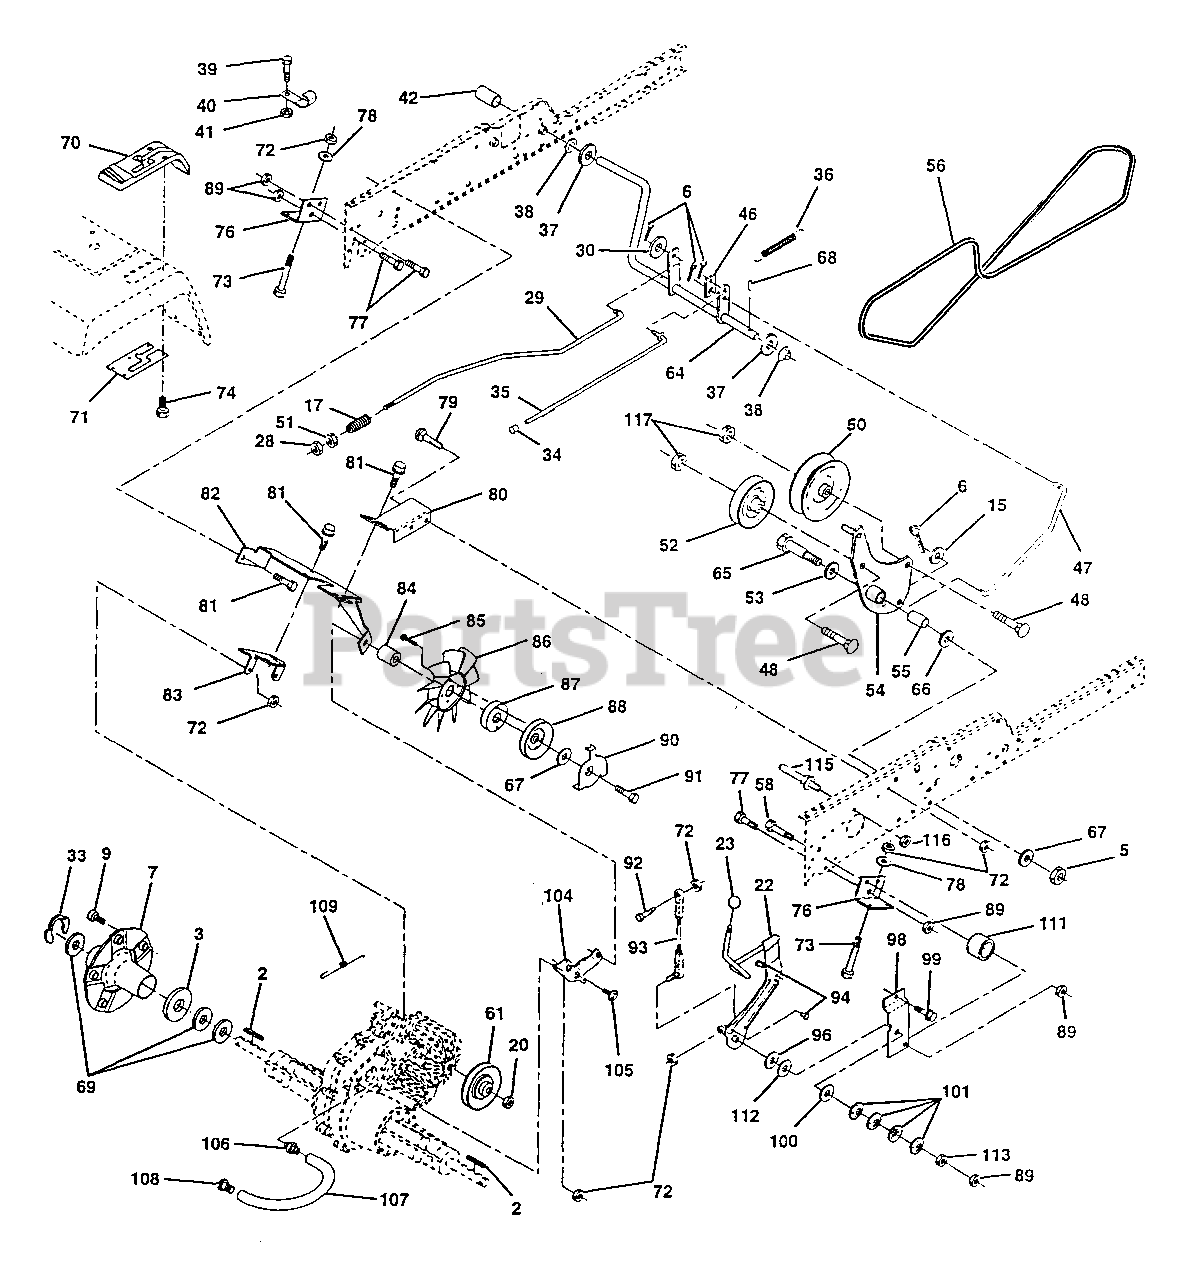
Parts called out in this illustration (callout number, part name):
2	Key 1/4 x 2.5
3	Washer Thrust Axle Harden
5	Nut Crownlock 3/8-16
6	Pin Cotter 1/8 x 3/4
7	Wheel Hub Asm.
9	Bolt Hub
15	Washer 13/32 x 13/16 x 16 Ga.
17	Spring Rod Brake
20	Nut Hex Jam Toplock 1/2-20
22	Shaft Arm Asm
23	Knob
28	Nut, Hex Jam 3/8-16
29	Brake Rod
30	Washer 13/32 x 1 x 14 Ga
33	Ring E
34	Cap Plunger
35	Rod Parking Brake
36	Spring Extension
37	Washer 25/32 x 1-1/4 x 16 Ga.
38	Nyliner
39	Screw Fin #10-24 x 1
40	Actuator Interlock Switch (AYP part number)
41	Nut Lock #10-24 (AYP part number)
42	Cover Pedal
46	Retainer Spring
47	Clutch Rod
48	Bolt Carriage 3/8-16 x 1-1/2 Gr. 5
50	Pulley Idler Flat (AYP part number)
51	Nut, Crownlock 3/8-16
52	Pulley Idler Grooved
53	Washer Hartdened
54	Clutch Arm Asm (AYP part number)
55	Bearing, Idler
56	V-Belt
58	Bolt Fin Hex 7/16-14 x 1-1/2
61	Pulley Transaxle
64	Shaft Asm Brake Parking Clutch
65	Bolt Shoulder
66	Washer Hardened
67	Washer 13/32 x 13/16 x 12 Ga
68	Pin Roll
69	Washer
70	Console Hydro Fender
71	Plate Console Shift
72	Locknut Hex W/Washer Insert
73	Bolt Fin Hex 5/16-18 x 3
74	Screw, Hex Wsh Hi-Lo 1/4-1/2
76	Bracket Transaxle
77	Bolt Fin Hex 7/16-14 x 1 (AYP part number)
78	Washer 11/32 x 3/4 x 12 Ga.
79	Bolt Carriage 5/16-18 x 5/8
80	Bracket Torque RH
81	Screw Thdrol 3/8-16 x 3/4
82	Bracket Mount Torque/Fan
83	Strap Torque Mid
84	Spacer
85	Screw #10-24 x 1-1/4
86	Fan 7" Hydro
87	Adapter Fan
88	Pulley Idler
89	Nut, Crownlock 7/16-14
90	Keeper Belt
91	Screw Thdrol 3/8-16 x 2-3/4
92	Bolt Fin Hex 5/16-18 x 1.75
93	Link Shift Asm
94	Fastner Christmas Tree
96	Washer Nickel Plated
98	Bracket Shift
99	Screw Thdrol 3/8-16 x 1-1/2
100	Washer Compression
101	Washer Bellville
104	Bracket Idler
105	Screw Tap 1/4-20 x 1/2
106	O-Ring Asm Hydro Gear
107	Line Fuel Hydro 15" VGT Serv
108	Cap Asm Vent Hydro Gear
109	Spring Return Brake
111	Spacer Shift Lever VGTH
112	Washer Nylon High Temp (AYP part number)
113	Nut Hex ASF 7/16-14 Unc
115	Keeper Belt T/A GND DR LR (AYP part number)
116	Nut Lock Hex Flange 5/16-18
117	Nut Lock Flg. 3/8-16 Unc (AYP part number)
